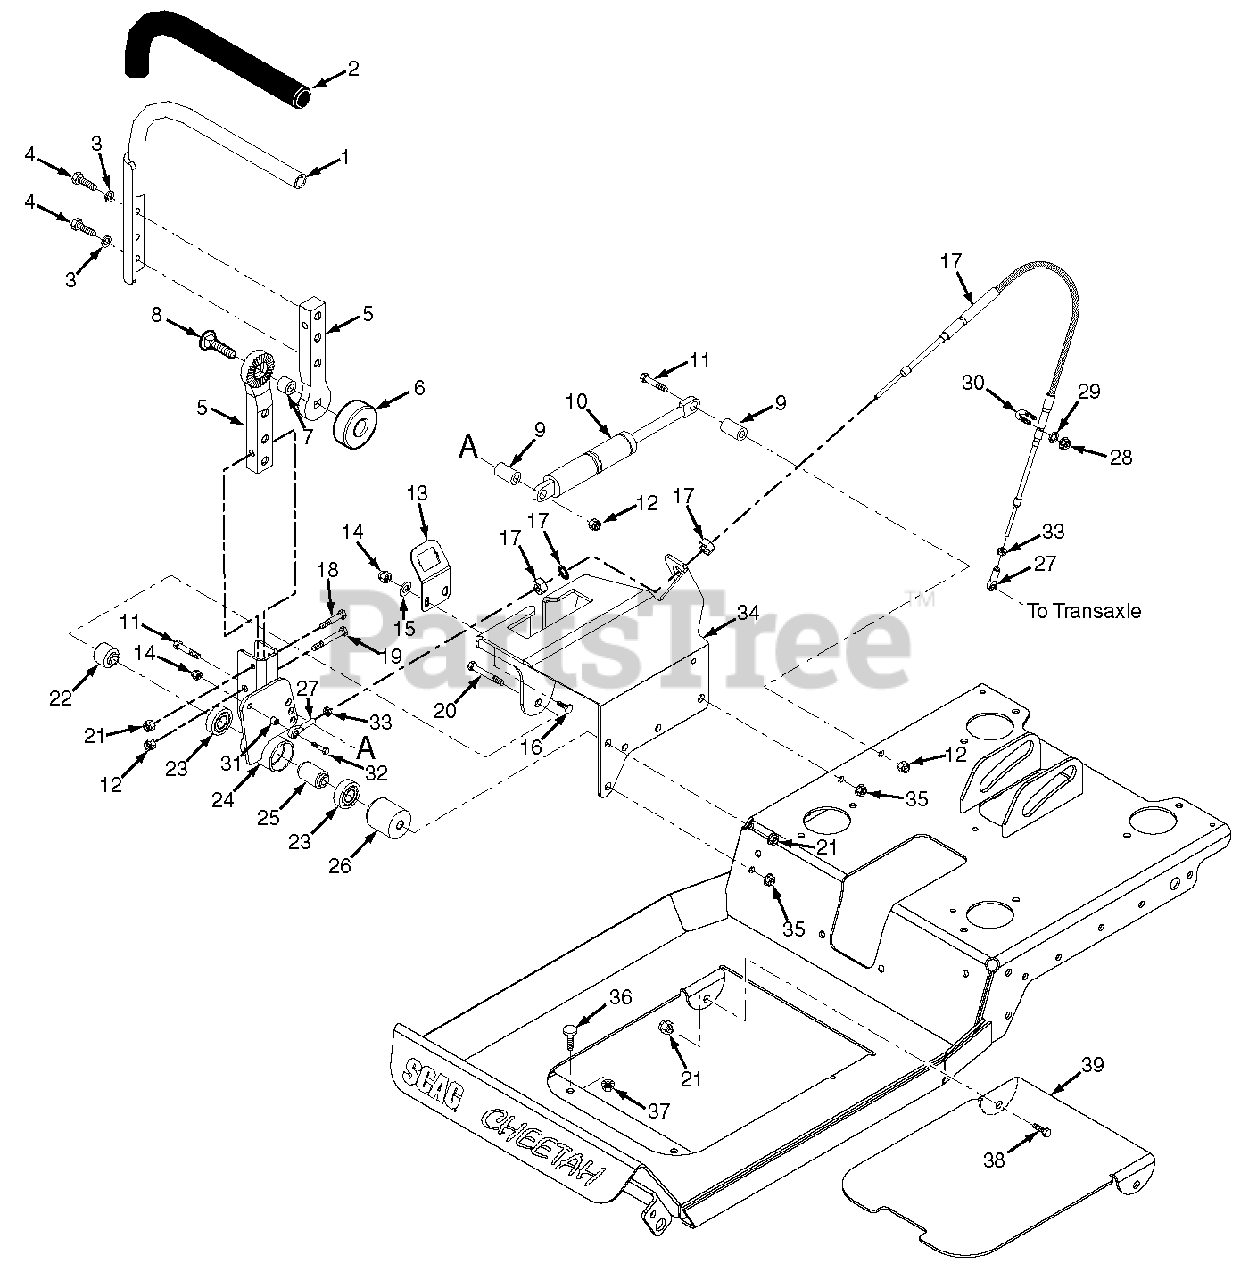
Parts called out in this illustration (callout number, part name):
1	Handle Bar w/Grip, LH
2	Grip, Control Handle
3	Lockwasher, 5/16-" Spring
4	Bolt, Hex Head 5/16-18 x 1'
5	Pivot, Control Lever
6	Knob, Control Handle
7	Spacer, Rubber
8	Bolt, Carriage 3/8-16 x 1-1/2"
9	Spacer
10	Damper
11	Bolt, Hex Head 5/16-18 x 2"
12	Nut, Elastic Stop 5/16-18
13	Bracket, Operator Presence Switch
14	Nut, Elastic Stop 1/4-20
15	Flatwasher, 1/4-.312 x .750 x .065
16	Bolt, Carriage 1/4-20 x 3/4"
17	Control Cable, Hydro
18	Bolt, Hex Head 3/8-16 x 2"
19	Bolt, Hex Head 5/16-18 x 2"
20	Bolt, Hex Head 3/8-16 x 6"
21	Nut, Elastic Stop 3/8-16
22	Spacer, Controls
23	Bearing
24	Pivot Weldment, Control Arm LH
25	Spacer, Bearing
26	Spacer, Controls
27	Rod End, 1/4-28 RH Thread
28	Nut, Jam 5/16-24 UNF-2B
29	Lockwasher, 5/16" Spring
30	U-Bolt, 5/16-24
31	Spacer
32	Bolt, Hex Head 1/4-20 x 1-1/4"
33	Nut, Jam 1/4-28 UNF
34	Bracket Weldment, Control Lever RH w/Decal
35	Nut, Serrated Flange 3/8-16
36	Bumper, Rubber
37	Nut, Serrated Flange 5/16-18
38	Bolt, Hex Head 3/8-16 x 1"
39	Cover, Footplate
